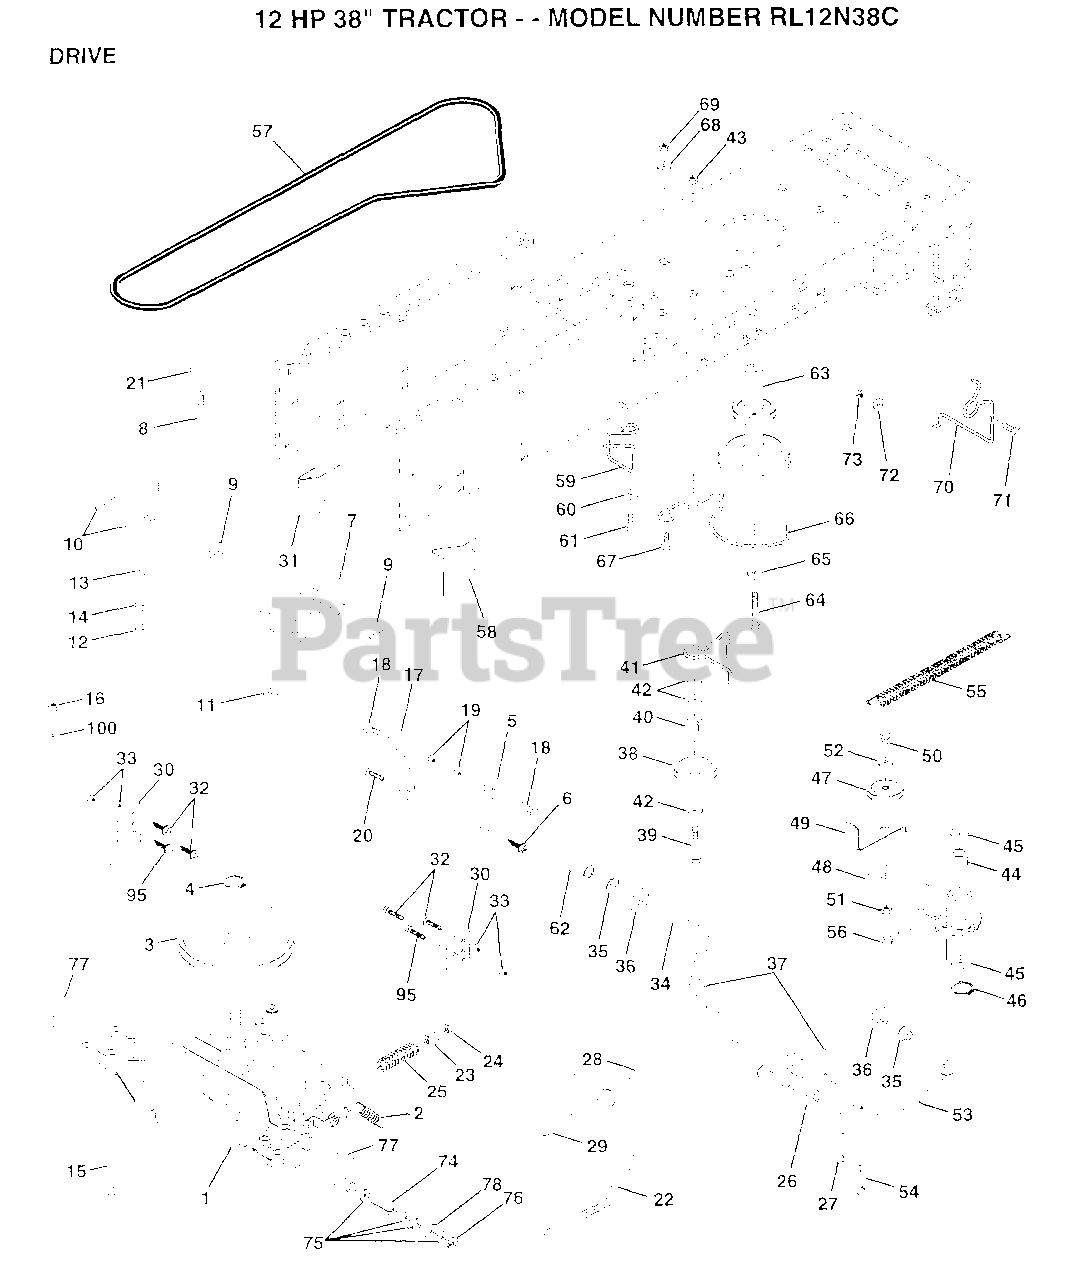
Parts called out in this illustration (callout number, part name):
3	PULLEY TRANS
5	STRAP TORQUE
6	SCREW
8	SHIFT ROD
9	WASHER
10	PIN COTTER 1/8
11	WASH-SHFT PLT LT
12	WASHER LT
14	LOCKWASHER
15	BOLT HEX
17	STRAP TORQUE
18	BOLT
19	NUT
20	SCREW
21	KNOB T (1/2-HOLE)
22	BRAKE ROD
23	NUT
24	NUT
25	SPRING ROD LT
26	WASHER
27	COTTER PIN
28	ROD PARK BRAKE
29	PLUNGER CAP T
30	TRANSAXLE MTG BKT
31	"KEEPER,BELT LH T"
32	BOLT
33	NUT
35	NYLON BEARING
36	WASHER LT
38	PULLEY.IDLER.FLAT
39	BOLT
40	SPACER T
41	BELT KEEPER LT
42	WASHER
43	NUT
44	"LY, BEARING"
45	WASHER LT
46	KLIP RING
48	ARM IDLER
49	RETAIN BELT
52	WASHER
53	"LINK, CLUTCH T"
54	COTTER PIN
55	"SPRING, RETURN LT"
56	COTTER PIN
58	"KEEPER,BELT RH T"
59	KEEPER BELT CNTSP
60	WASHER
61	SCREW
62	PEDAL COVER T
63	PULLEY.ENGINE
64	BOLT
65	LOCKWASHER
66	KEEPER.BELT.ENG.L
67	BOLT
68	WASHER
70	KEEPER BELT ENG
71	BOLT
72	WASHER
74	SPACER LT
75	WASHER
76	E-RING LT
77	SQUARE KEY
78	WASHER
95	SCREW
100	WASHER M
